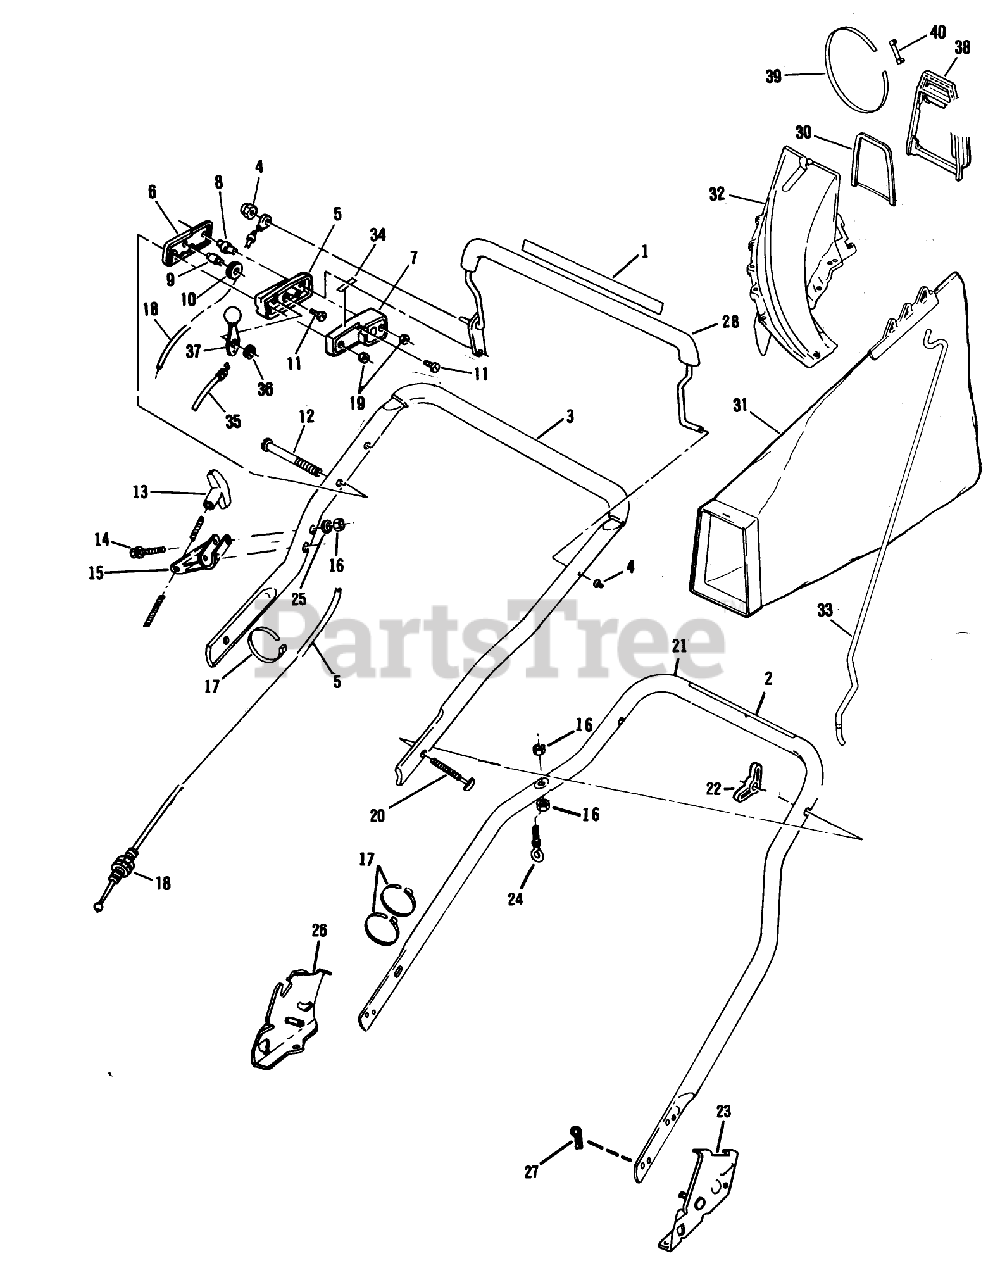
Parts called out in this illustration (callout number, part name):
8	COLUMN
9	PIN SKF
10	PULLEY PL
11	SCREW
12	SCREW
13	HANDLE START UM&D
16	LOCKNUT E
18	CONTROL CABLE WES
19	NUT C/LOCK E
20	BOLT QUALITY
22	NUT-WING
24	EYE BOLT WAS MFG
25	WASHER
27	HAIR PIN
29	NUT ACORN
30	CHUTE BRACE
31	ORD 89816 WHOLE GOODS
33	ROD GRASSBAG
35	CABLE TH'TTLE WES
36	WASHER-SPRING
37	LEVER&KNOB AY WES
38	CHUTE - ADAPTER
